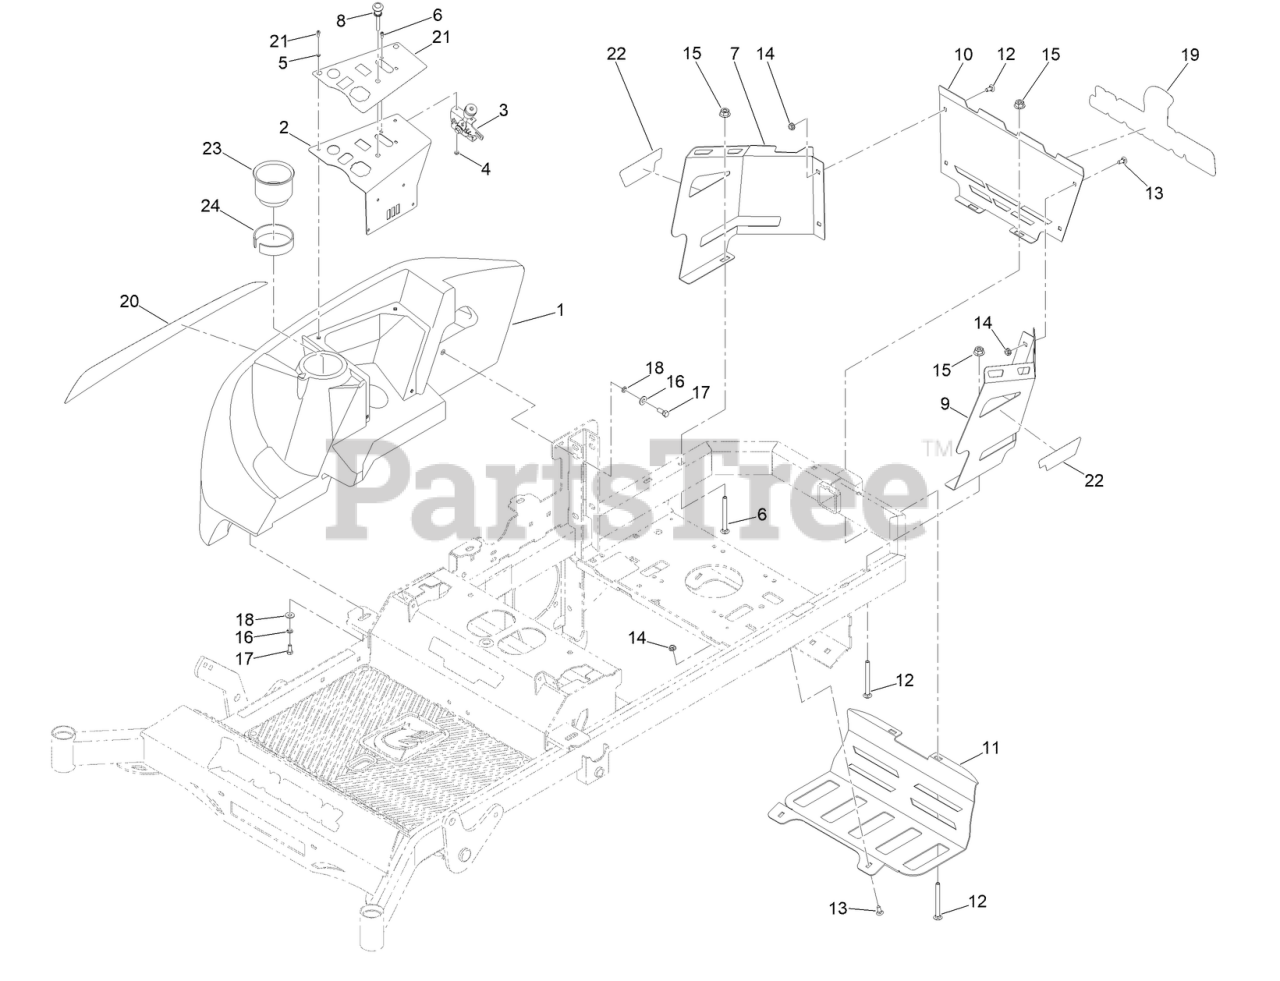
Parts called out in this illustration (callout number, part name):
1	CONSOLE W/ CUPHOLDER
2	CONTROL PANEL BRKT INDIV CONTROLS PAINT
3	MWR THROTTLE CABLE ASSY W / HANDLE
4	NUT-LOCK
5	#10 SPLIT LOCKWASHER 18-8 SS
6	10-24 X 1/2 SOCKET C/S 18-8 SS
7	2021 RT/SRT ENGN COWLING RTPAINTED
8	MWR CHOKE CABLE ASSM
9	2021 RT/SRT ENGN COWLING LT PAINTED
10	PLATE - ENGINE COWLING
11	MUFFLER GUARD [GRAY]
12	3/8-16 X 4 CARRIAGE BOLT ZINC
13	BOLT-CARR
16	WASHER-FLAT
17	SCREW-HH
18	WASHER-LOCK
19	MWR RR SPARTAN LOGO
20	DECAL-TANK
21	DECAL- CONSOLE, KEYSWITCH
22	RT-PRO MODEL DECAL
23	CUP HOLDER
24	TAPE-FOAM
